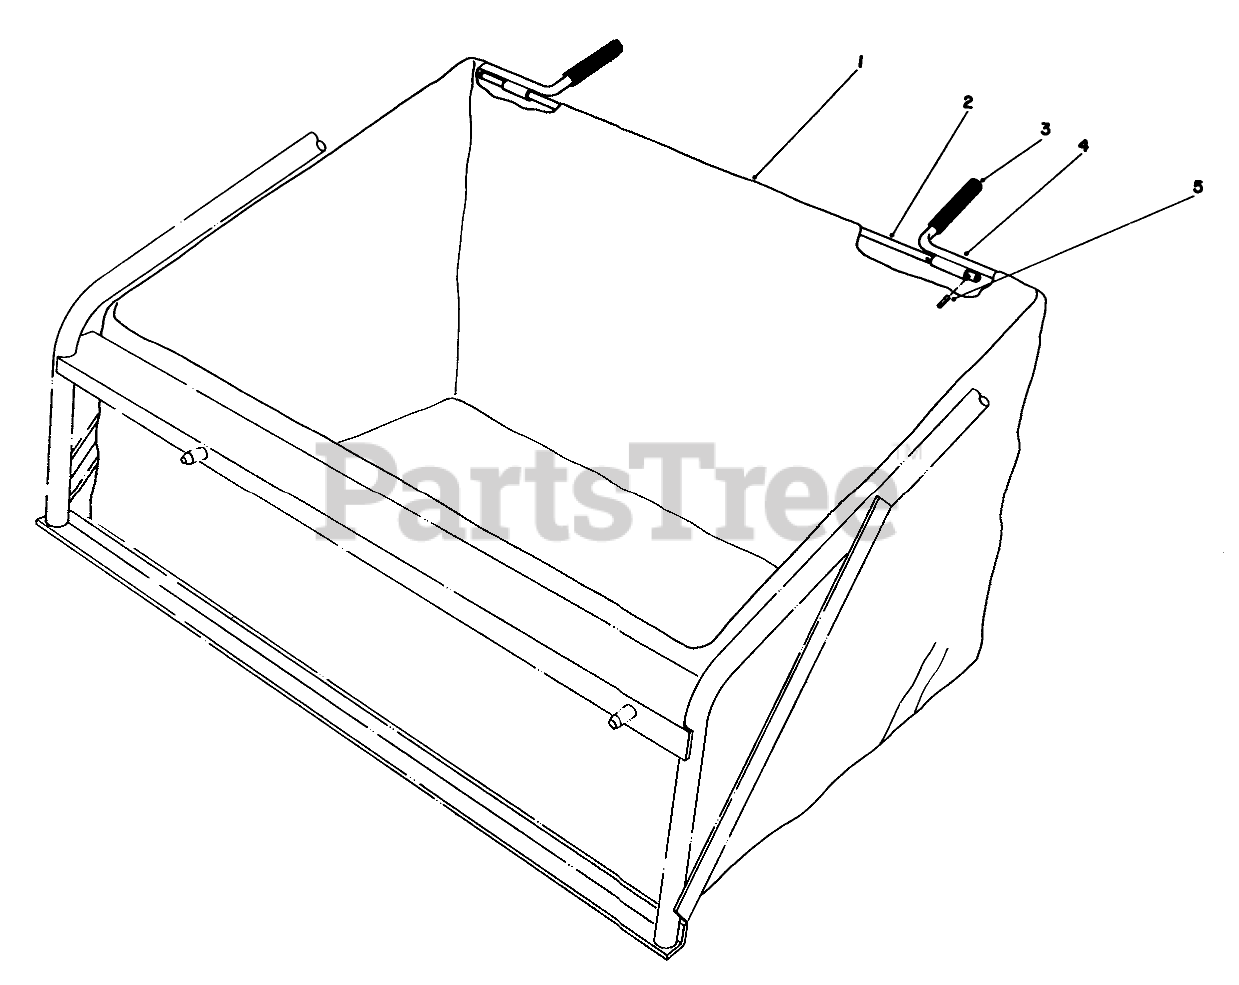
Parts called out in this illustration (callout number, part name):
1	Bag-Leaf Catcher
2	Rod-Bag Frame
3	Grip-Leaf Bag Handle
4	BAG FRAME WA B
5	PIN-ROLL
